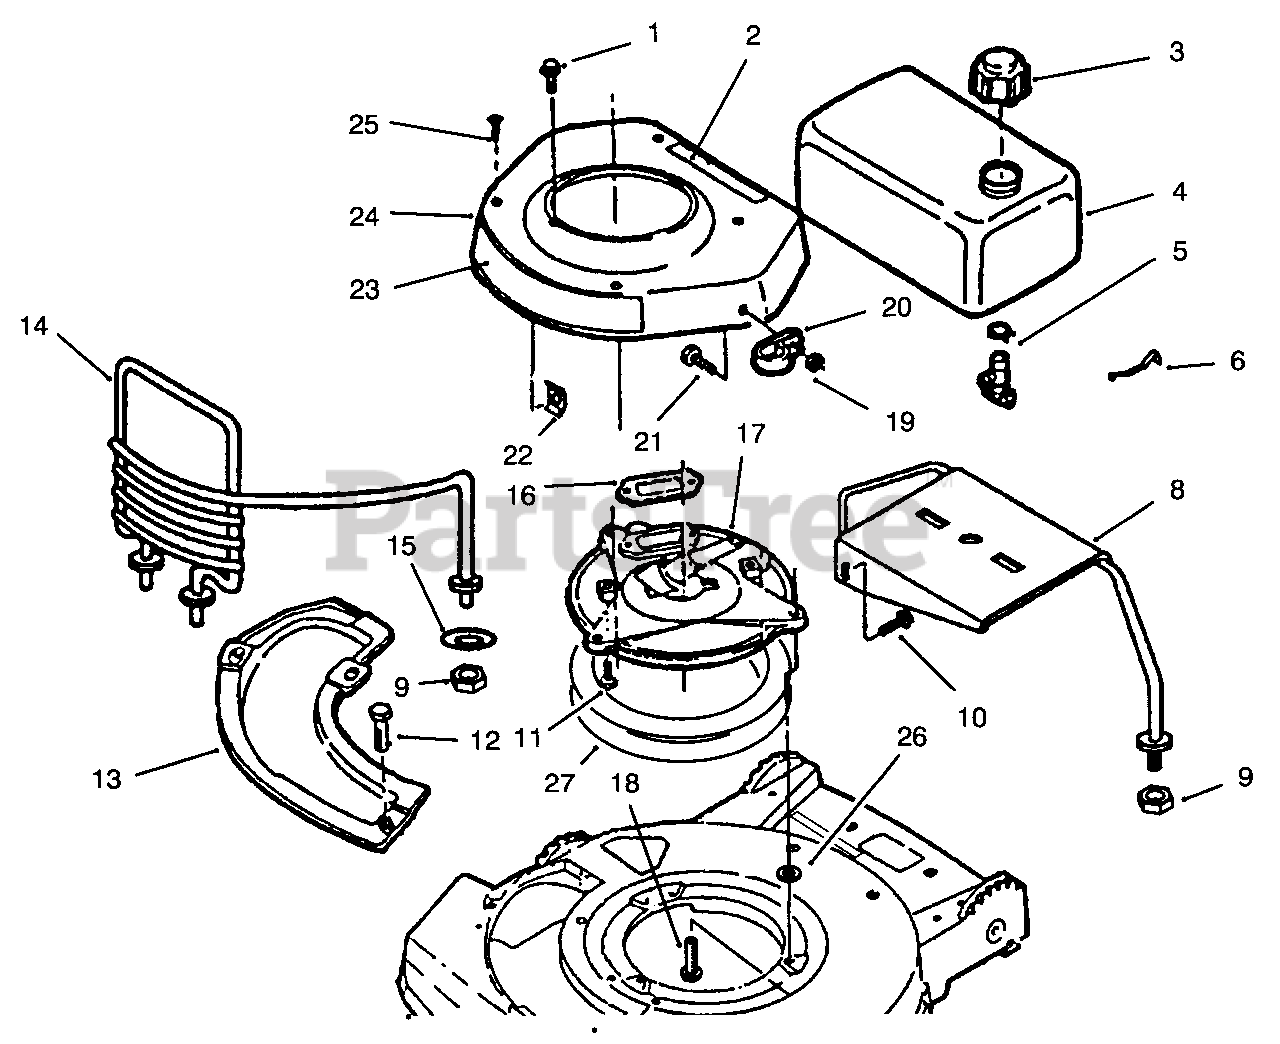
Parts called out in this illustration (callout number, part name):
1	Screw-Starter
2	Decal-Mixture, Fuel
3	Assembly-Cap, Fuel
4	Tank-Fuel
5	Clamp-Valve to Tank
6	Spring-Mount., Fuel Tank
7	Valve & Screen-Shut-Off
8	Bracket-Tank, Fuel
10	Screw-Hex Hd. Cap
11	Screw-Muffler Plate to Block
12	Screw-Hex Hd.
13	Plate-Cover
14	Guard-Engine
16	Gasket-Exhaust
17	Plate-Muffler
18	Screw-Muffler Plate to Housing
19	Nut-Lock
21	Screw-Clamp to Shroud
22	Retainer-Applique
23	Applique
25	Screw-Shroud to Base
26	Washer-Flat
27	Plate-Engine
